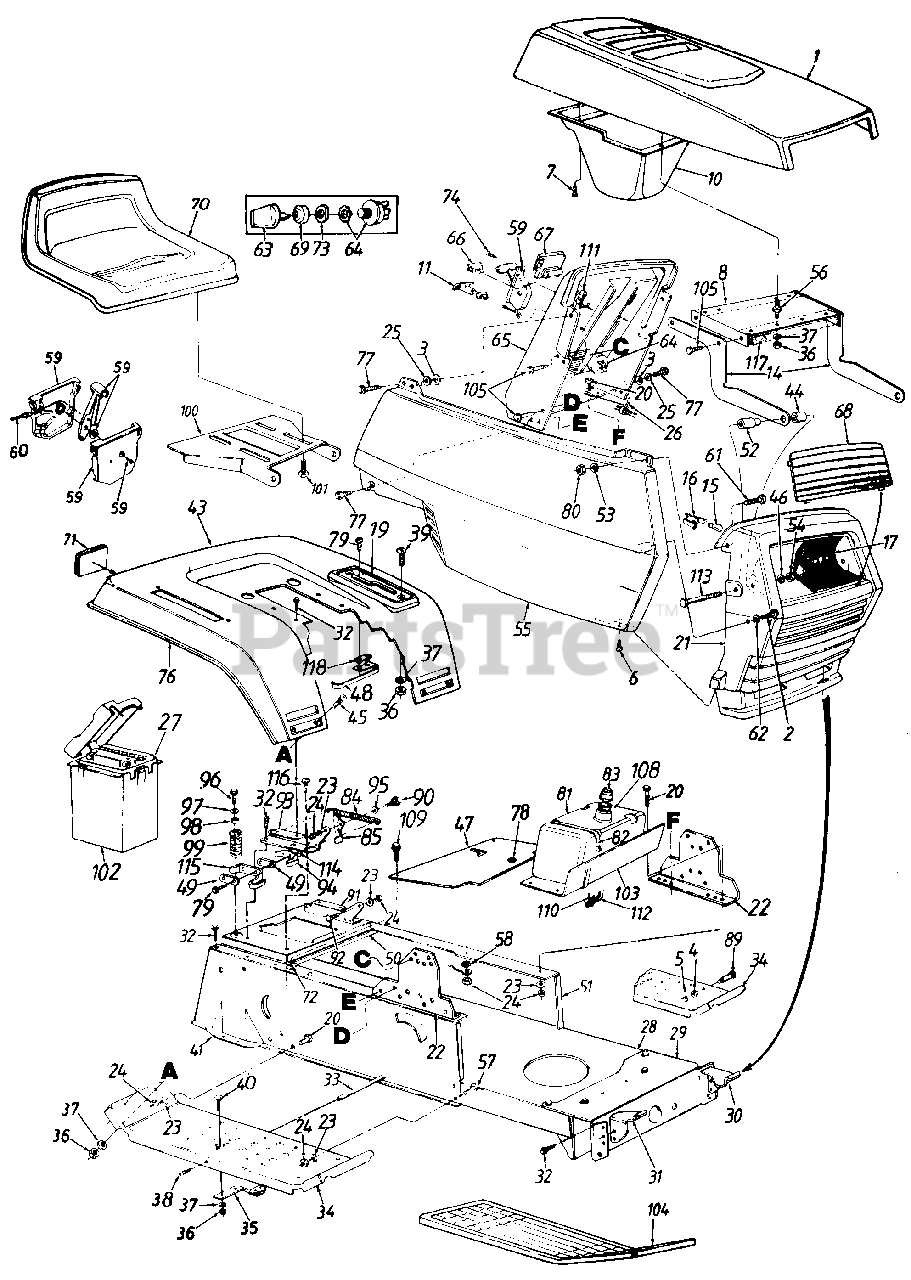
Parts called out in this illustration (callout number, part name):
3	Bolt Retainer 1/4" I.D.
4	L-Wash. 3/8" I.D.
5	Hex Nut 3/8-16 Thd.
6	Truss Mach. AB-Tap Scr. #10 x .5" Lg.
7	Hex Wash Hd. AB-Tap Scr. #8 x .5" Lg.
8	Hood Plate
11	Choke Control 29" Lg.
14	Hood Hinge
15	Lamp
16	Twist Lock-Lamp Socket
17	Reflector-Headlight
19	Speed Control Index Brkt.
20	Hex Bolt 5/16-18 x .75" Lg.
21	Grille
22	Dash Support Bracket
23	L-Wash. 5/16" I.D.
24	Hex Nut 5/16-18 Thd.
25	Fl-Wash. 1/4" I.D. x .93" O.D.
26	Cable Tie
27	12 Volt Battery
28	Lower Frame
29	Front Pivot Brk't.
30	Grille Mount Brk't.-L.H.
31	Grille Mount Brk't.-R.H.
32	Hex Wash. Hd. AB-Tap Scr. 5/16 x .75" Lg.
33	Running Board Rod
34	Running Board
35	Blade Brake Ass'y.
36	Hex Nut 1/4-20 Thd.
37	L-Wash. 1/4" l.D.
38	Truss Mach. Scr. 5/16-18 x .75"
39	Truss Mach. Scr. 1/4-20 x .75" Lg
40	Carr. Bolt 1/4-20 x .62"
41	R.H. Side Frame
45	Carriage Bolt 1/4-20 x .50" Lg.
46	Fl-Wash. .328" I.D. x .68" O.D.
47	Transmission Panel
48	Reverse Safety Switch
49	Insulator Plate
50	Hitch Plate
51	L.H. Side Frame
52	Shld. Spacer .33" I.D.
53	Fl-Wash. .281" I.D. x .5" O.D.
54	Hex Cent. L-Nut 5/16-18 Thd.
55	Side Cover-R.H.
56	Double Ended Stud 1/4-20 Thd.
57	Hex Wash. Hd. Scr. 5/16-18 x 37" Lg
58	Ext. L-Wash. 5/16" I.D.
59	Throttle Control Box Ass'y.
60	Throttle Control Wire 18.5" Lg.
61	Hex Bolt 1/4-20 x .62" Lg.
62	Fl-Wash. .281" I.D. x .731' O.D.
64	Ignition Switch
66	Light Switch
67	Ammeter
68	Lens
69	Ignition Switch Cap
70	Seat Ass'y.
71	Reflector
72	Speed Nut #10Z
73	Ignition Switch Nut
74	Truss Mach. AB-Tap Scr. #10 x 5" Lg.
76	Trim Strip-81n
77	Hex Wash. Hd. Tap Scr. 1/4 X 75" Lg.
78	Snap Bushing
79	Hex Wash. Hd. AB-Tap Scr. #8 x 50" Lg.
80	Hex L-Nut 1/4-20 Thd.
81	Fuel Tank
82	Cable Tie
83	Fuel Cap w/o Gasket
84	Ext. Spring 5.31" Lg.
85	Seat Lift Brkt.
89	Shoulder Bolt
90	Shld. Bolt .437" Dia. x .26811
95	Spr.-Wash..445" I.D.
96	Hex Wash. Hd. Tap Scr. 5/16-18 x 11' Lg.
97	Fl-Wash. .344" I.D.
99	Compression Spring
100	Seat Pivot Bracket
101	Hex Tap Scr. 3/8-16 x .75
102	Battery Box
103	Gasoline Tank Support
104	Foot Pad-L.H.
105	Hex Tap Scr. 1/4-20 X .51' Lg.
108	Fuel Cap Gasket
109	Truss Mach. Tap Scr. #10 x .51" Lg.
111	Speed Nut 1/4-20 Thd.
112	Fuel Line
113	Hex Bolt 5/16-18 x 2.75"
114	Insulator Boss Plate
115	Spring Switch
116	Truss Mach. Scr. 5/16-18 x .75
118	Insulator Nut Plate
